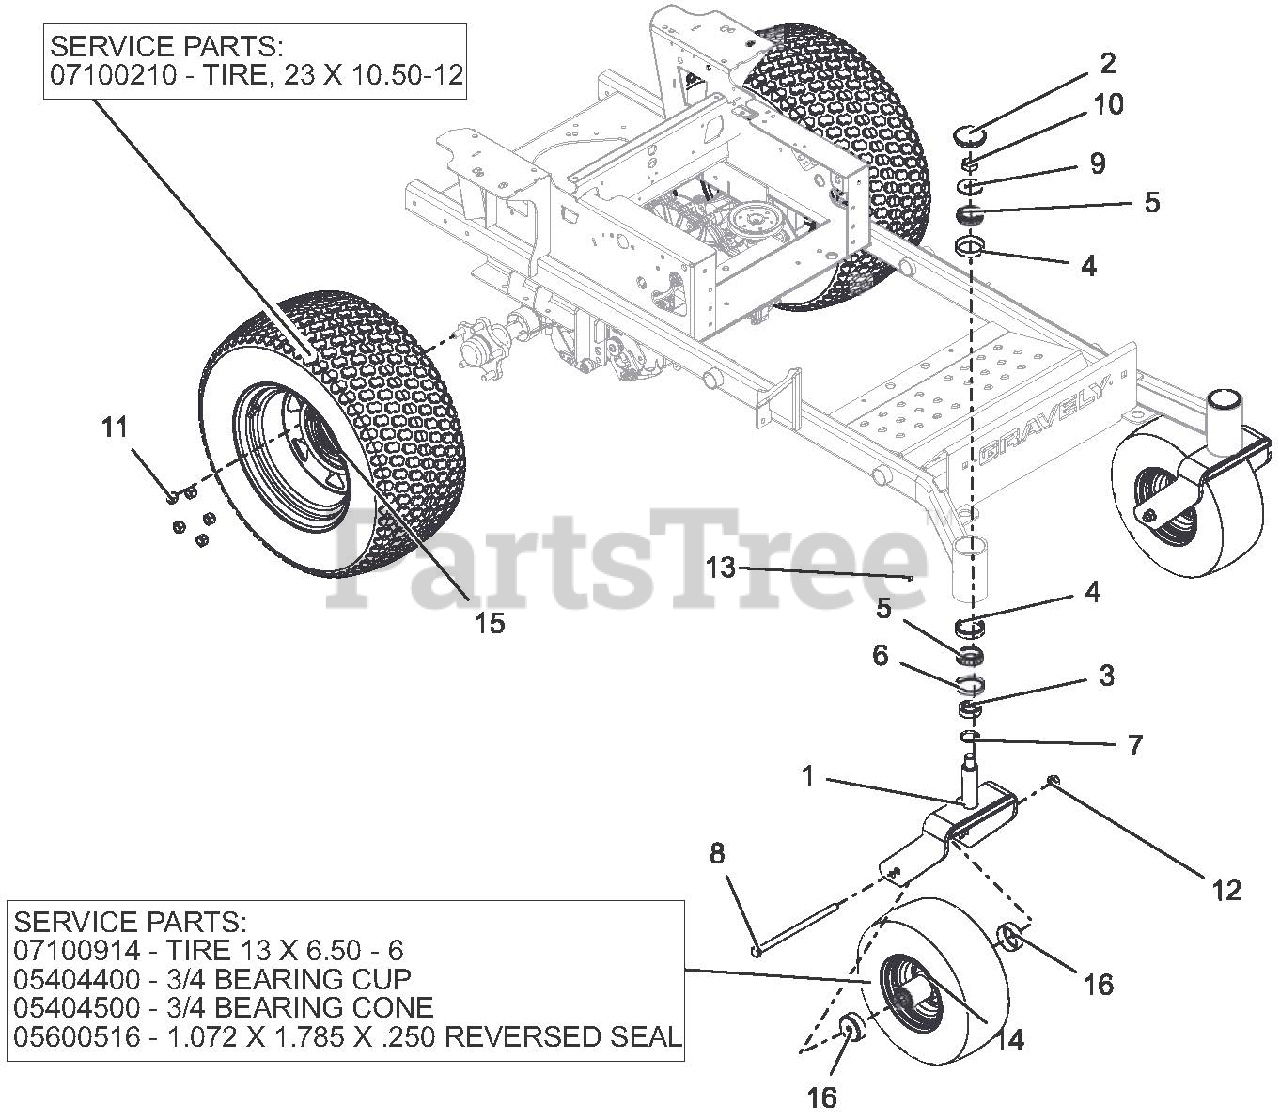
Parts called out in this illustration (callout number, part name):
1	WMT, CASTER FORK - RED
2	CAP, DUST
3	SPCR, FRONT CASTER FORK
4	BRG, CUP 2.328 X .465
5	BRG, CONE 1.250 X .660
6	SEAL, OIL 1.75 X 2.332 X .312
7	O-RING, .139 W X 1.234 ID
8	BLT-HEX .50-13 X 9.00 GR5 YWZC
9	WSHR-FL-STL .812 X 2.00 X .148 YWZC
10	NUT-LK-TOP-JAM.75-16 YWZC
11	NUT, LUG .500-13
12	NUT, LK-TOP-FLG .50-13 YWZC
13	FITTING, .250-28 FLUSH MOUNT GREASE
14	ASSM TIRE/WHEEL, 13 X 6.50-6 SMOOTH
14	TIRE 13 X 6.50-6
14	3/4 BEARING CUP
14	3/4 BEARING CONE
14	1.072 X 1.785 X .250 REVERSED SEAL
15	ASSM TIRE/WHEEL 23 X 10.50-12
15	TIRE, 23 X 10.50-12
16	SHIELD, WHEEL BEARING
